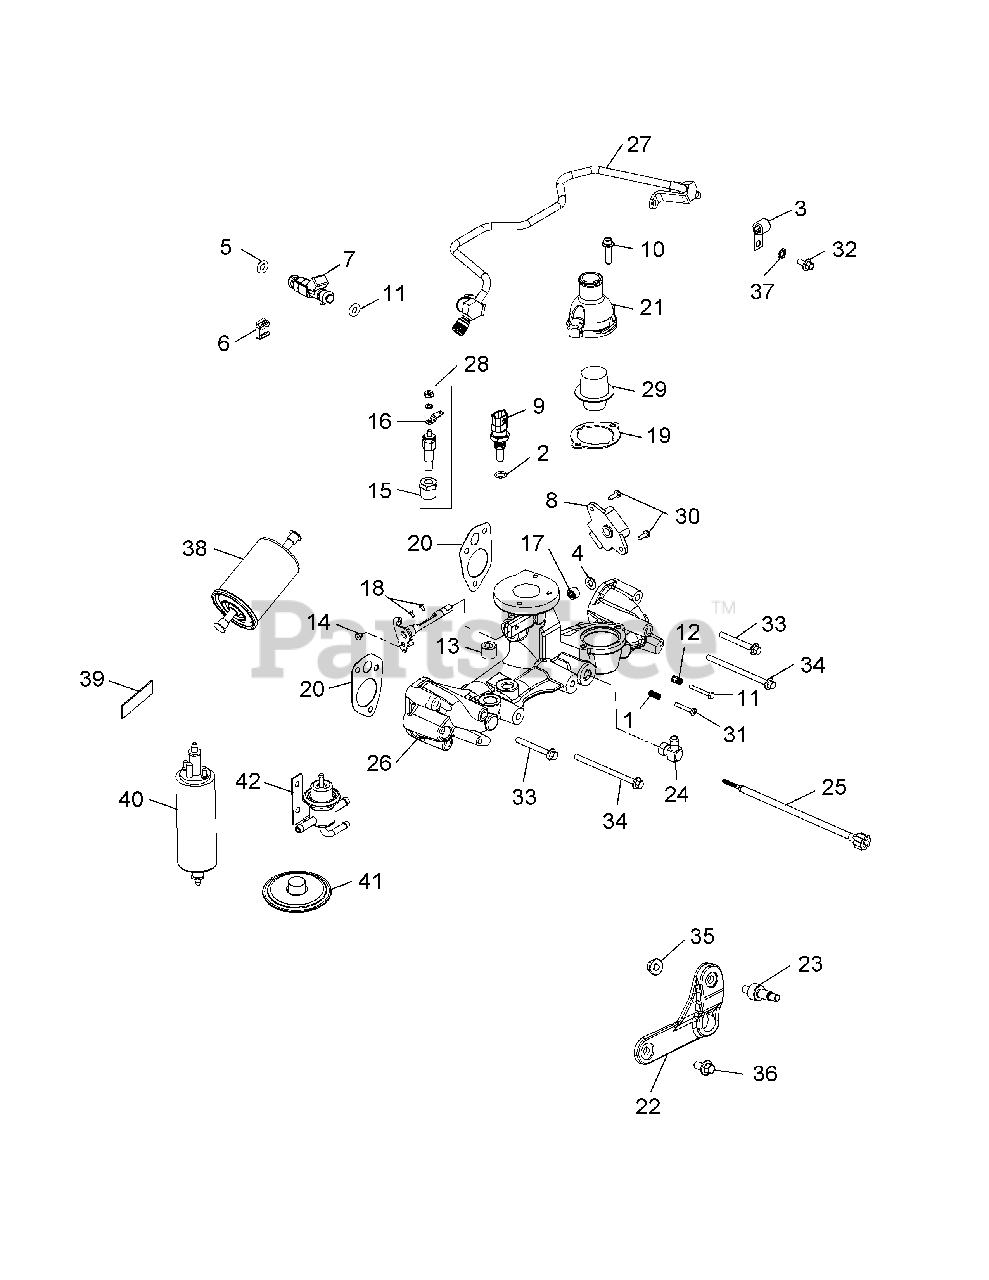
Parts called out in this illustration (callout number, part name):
1	Spring, Speed Control (Short)
2	O-Ring (.5" Dia)
4	Seal, Throttle Shaft
6	Clip, Fuel Injector
7	Injector, Fuel
8	Kit, Throttle Position Sensor
9	Sensor, Temperature
10	Screw, Flg M6x1.0x25
12	Spring, Idle Set Screw
13	Plug, Pipe Ctsk 3/8"
14	Bushing, Linkage Retaining
17	Bearing, Needle
19	Gasket, Thermostat
20	Gasket, Intake Manifold
21	Housing, Thermostat
24	Connector, Hose
26	Kit, Efi Intake Manifold
29	Kit, Thermostat
30	Screw, Phl Pan M4x0.7x12
31	Screw, Phl Pan M4x0.7x25
32	Screw, Flg M6x1.0x12
33	Screw, Flg M6x1.0x50
34	Screw, Flg M6x1.0x90
36	Screw, Flg 8X1.25x16
38	Fuel Filter, High Pressure
